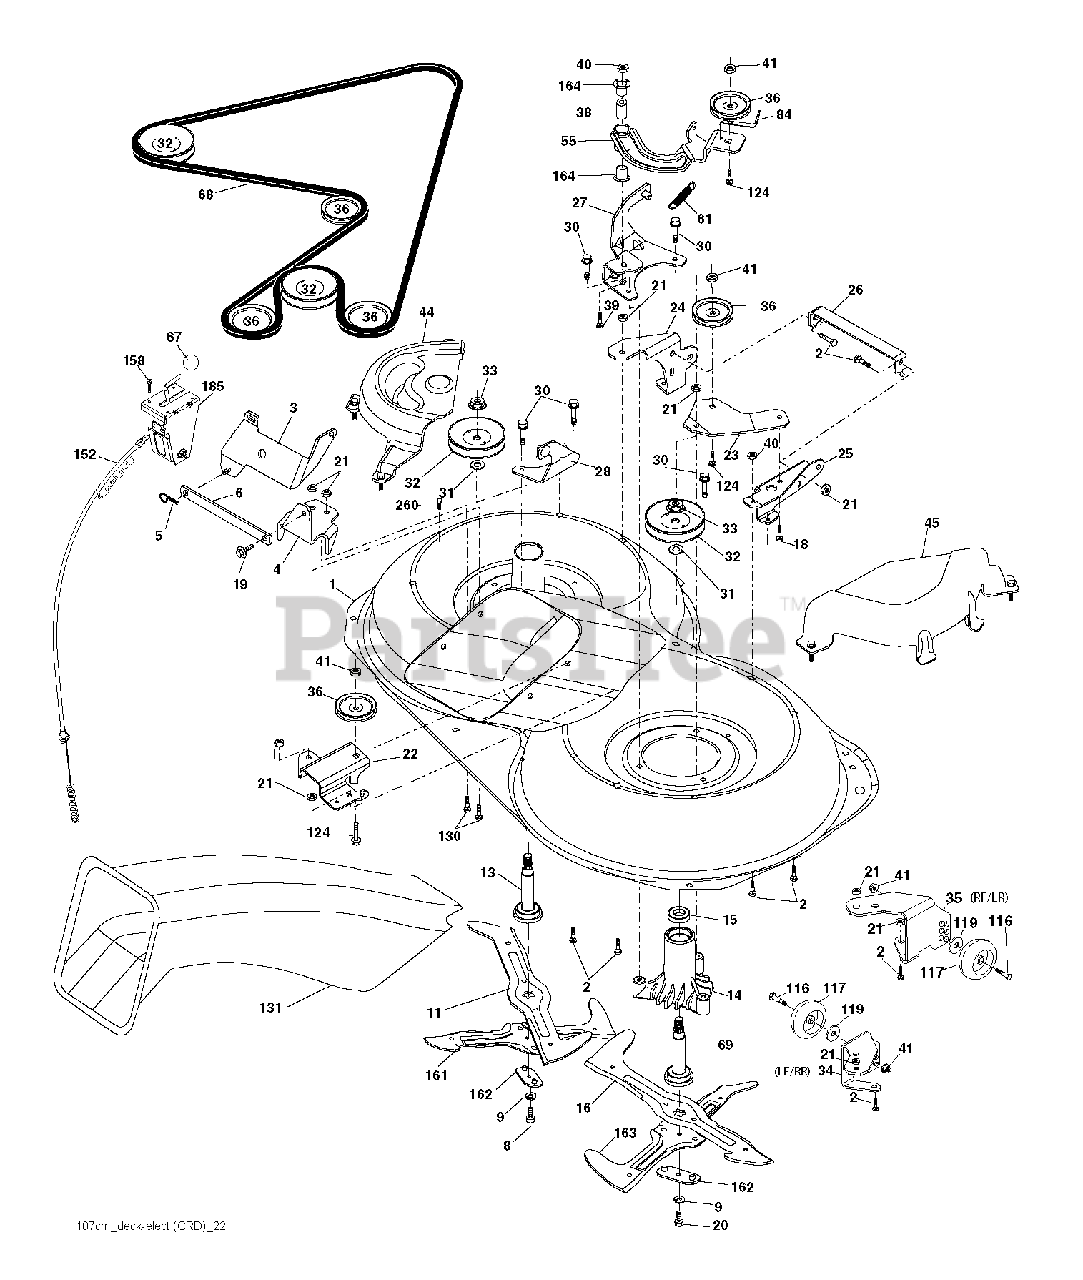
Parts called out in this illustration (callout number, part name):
2	BOLT
3	BRACKET.ASM.BAR.SWAY.CHASS
5	RETAINER-SPRNG RB
6	BAR SWAY
8	Bolt, 3/8-24 X 1.25 Gr8
9	LOCKWASHER
11	BLADE.3N1.LH.CRD
13	SHAFT ASM VENT
16	BLADE.3N1.RH.CRD
19	BOLT SHD 5/16-18
20	BOLT.3/8-24X1.25GR8. LHTHRD
21	LOCKNUT
22	BRACKET
23	BRACKET
27	BRACKET
30	SCREW, WASHER HEAD
31	WASHER.SPACER.MANDREL
33	NUT.FLANGE.LOCK.TOP
36	PULLEY.IDLER.4.25
40	LOCKNUT
41	NUT LOCK FLG 3/8-16 UNC
67	KNOB T (3/8 HOLE)
68	HEX-BELT 107 MOWER
69	SHAFT.ASM.W/LWR.BRG.RH.THREAD
84	KEEPER, BELT IDLER
116	BOLT.SHOULDER.3/8-16X3-5/8
117	WHEEL. GUAGE RALLY
124	BOLT.3/8-16X1.50
158	SCREW
164	BRNG T
185	HEAD ASM. CABLE CLUTCH
260	SCREW 3/8-16X1/2
